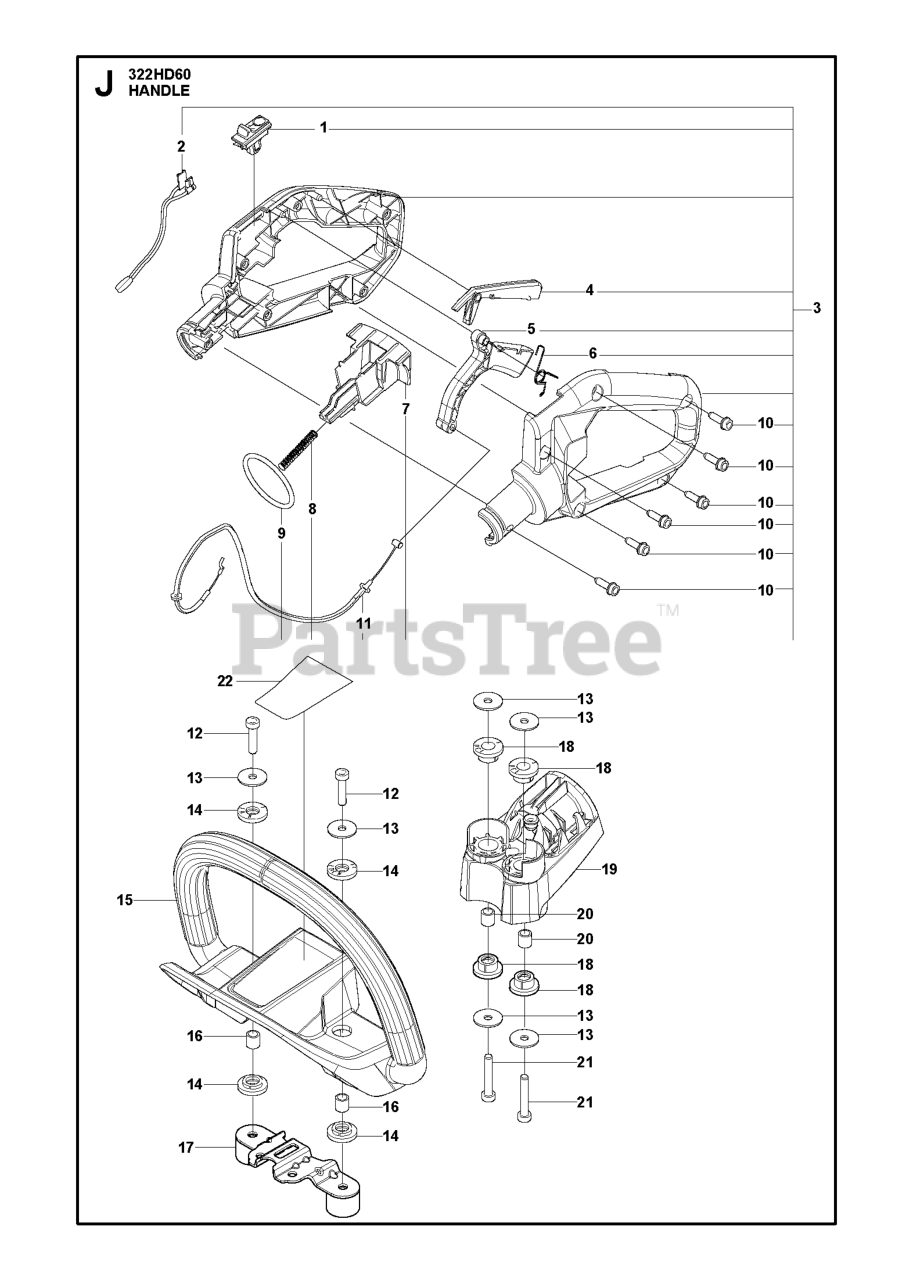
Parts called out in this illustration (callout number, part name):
1	STOP BUTTON
2	SHORT CIRCUIT CABLE
4	THROTTLE LOCKOUT
5	THROTTLE CONTROL
7	LOCKING BUTTON
8	RECOIL SPRING
11	THROTTLE CABLE ASSY
14	ANTIVIBRATION ELEMENT
18	ANTIVIBRATION ELEMENT
19	HANDLE HOLDER
